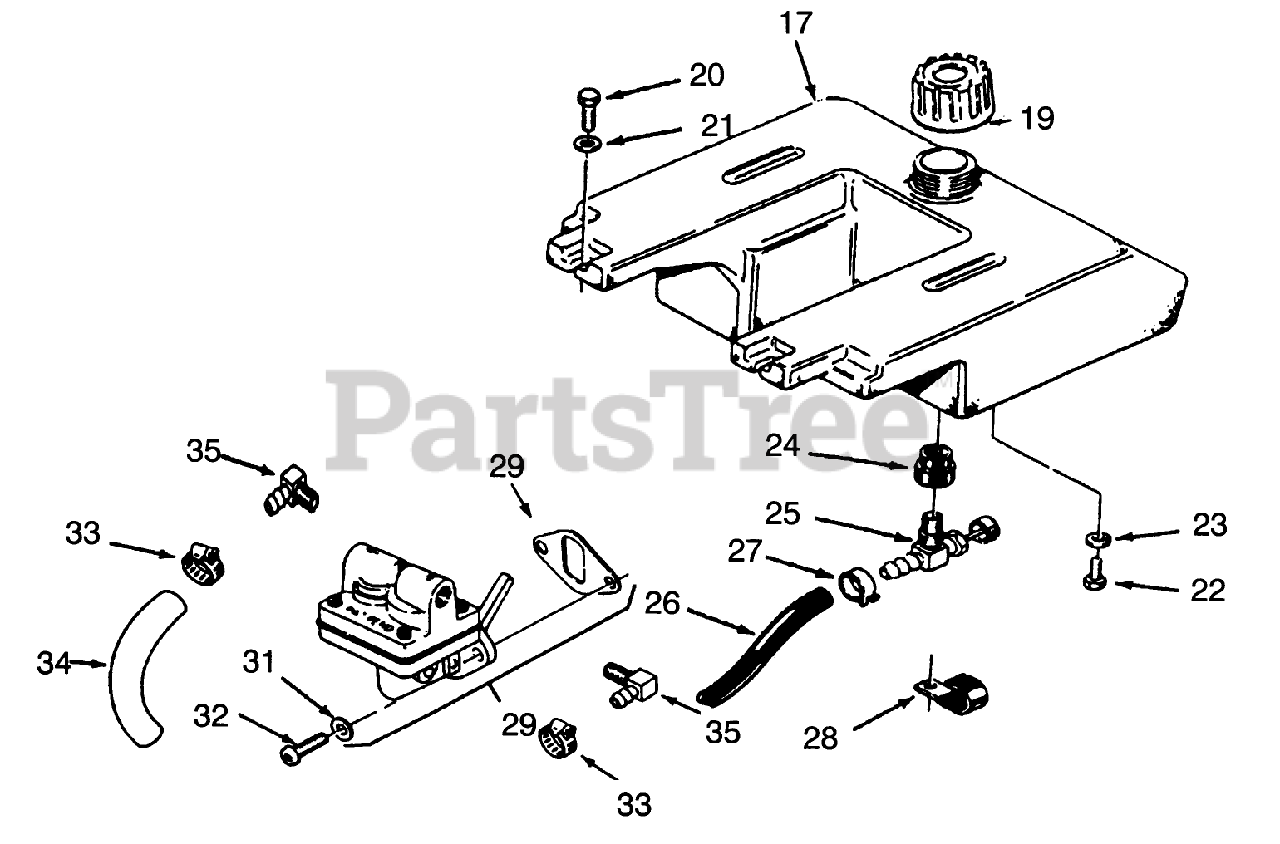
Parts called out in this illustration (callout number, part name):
17	TANK-FUEL
19	GAS CAP ASM
21	WASHER-FLAT
22	SCREW-HH
23	WASHER-LOCK
25	VALVE-FUEL
29	KOHLER 47-559-08
30	KOHLER 25-041-05
31	KOHLER X-25-63
32	KOHLER X-174-2
33	KOHLER X-426-9
34	KOHLER 25-353-01
35	KOHLER 25-155-02
